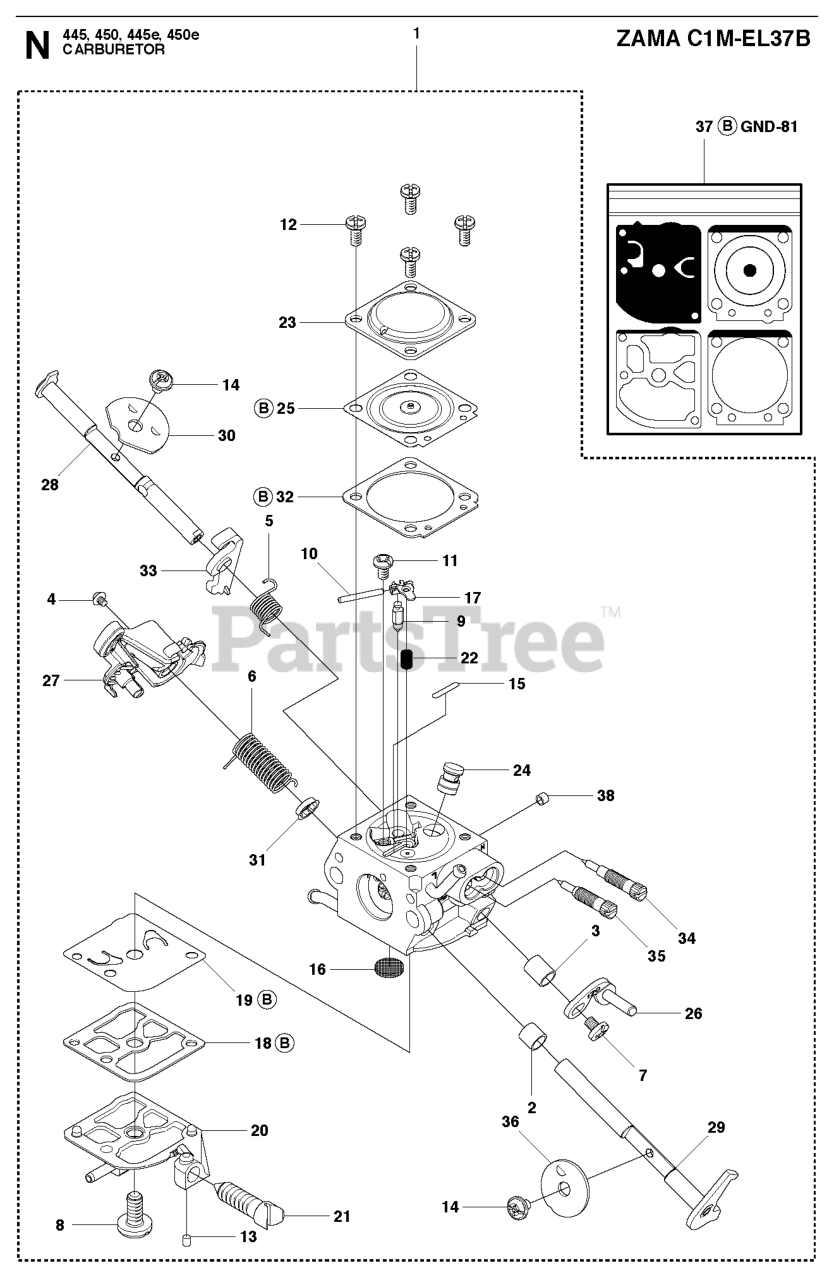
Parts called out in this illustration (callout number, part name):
1	CARBURETOR
9	INLET NEEDLE
10	PIN RETAINING SCREW
19	PUMP DIAPHRAGM
27	THROTTLE LEVER
28	SHAFT ASSY
29	SHAFT ASSY
30	CHOKE VALVE
37	GASKET KIT
